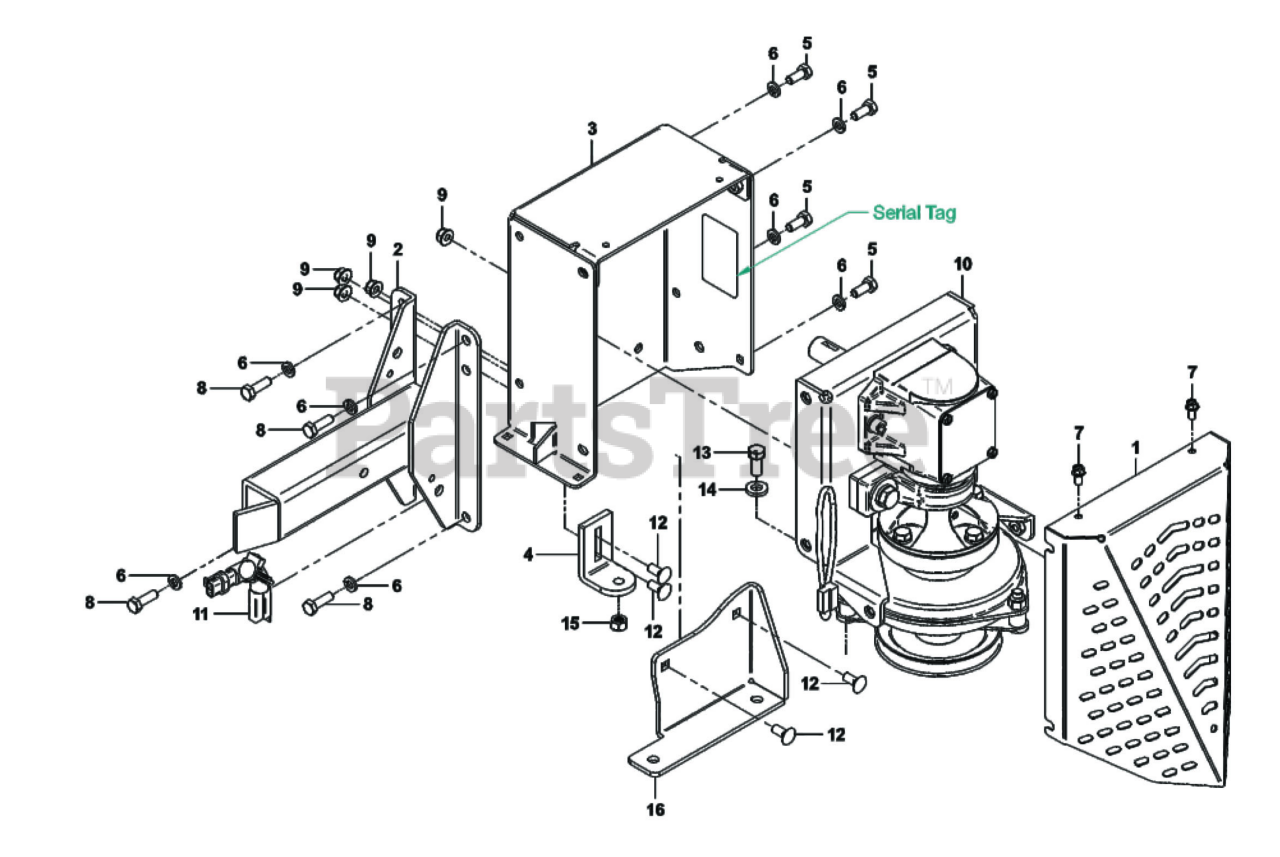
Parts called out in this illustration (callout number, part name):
1	DRIVE GUARD
2	DRIVE ARM ASSEMBLY
3	HOUSING MOUNT ASSEMBLY
4	ANTI-ROTATION BRACKET
5	HEX SCREW HEAD 5/1
6	LOCK WASHER 5/16"
7	HEX SCREW HEAD 1/4
8	HEX SCREW HEAD 5/1
9	NUT-FLANGE LOCK 5/
10	MOUNTED DRIVE ASSEMBLY
11	JUMPER HARNESS (W/DIODE)
12	SCREW 5/16"-18 X .75" GR8
13	SCREW 3/8"-16 x .875" (GR8)
14	FLAT WASHER
15	REVERSE GD "C" LOCK NUT (3/8-16)
16	PLATE-IDLER ASSY MOUNT
